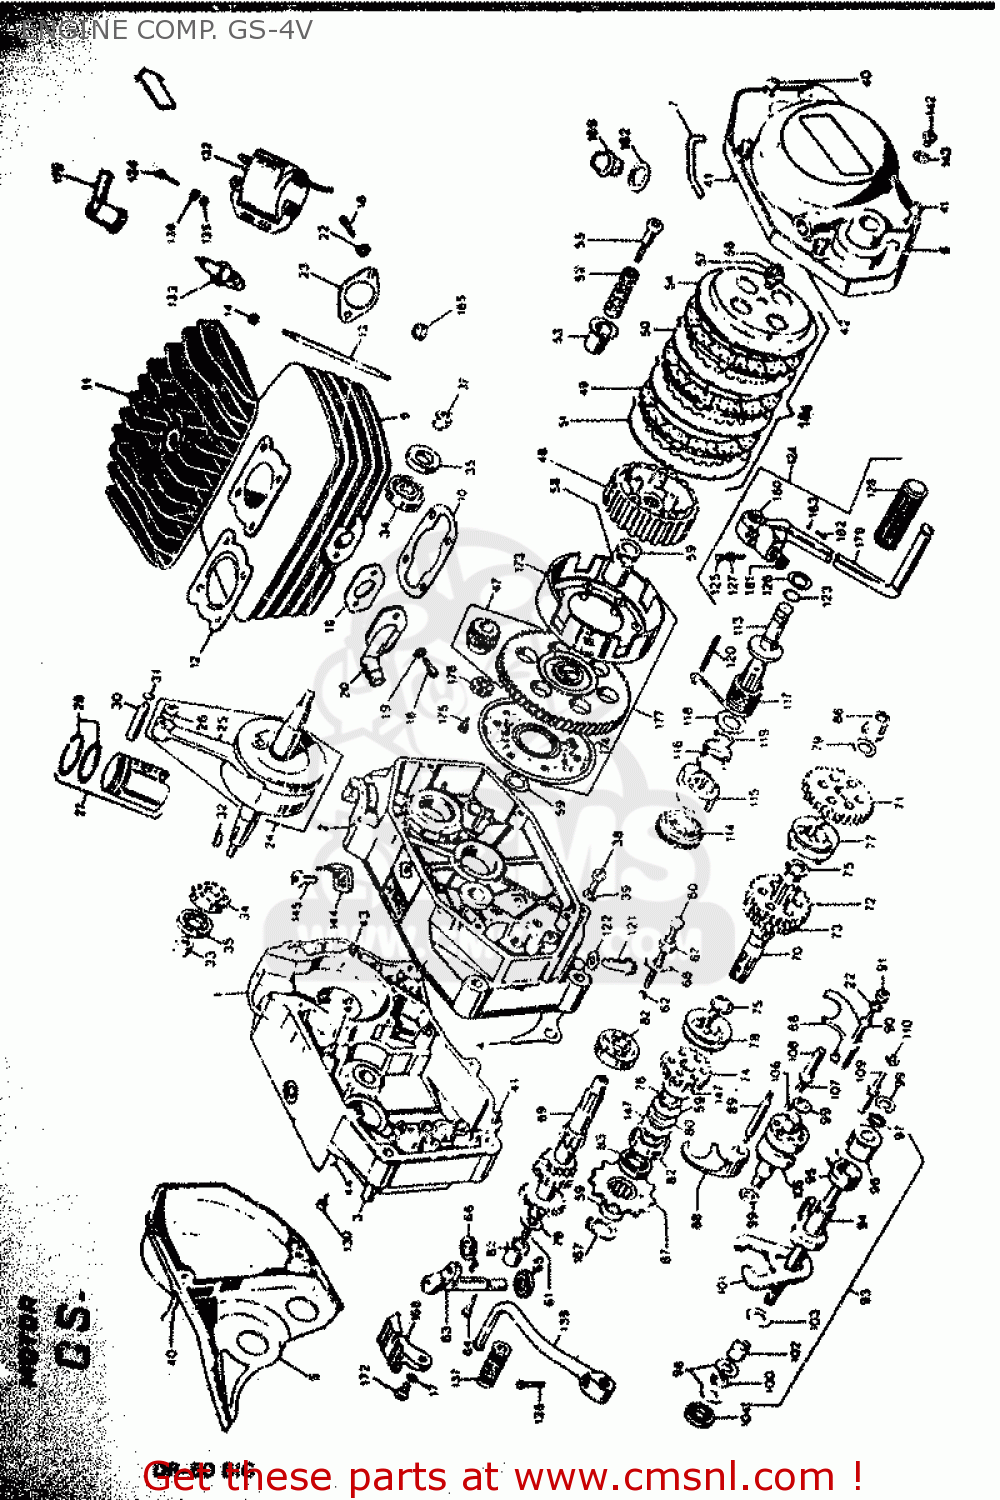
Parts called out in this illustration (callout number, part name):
1	2
2	3
3	PIN
4	GASKET
5	COVER, MAGNETO
6	COVER, CLUTCH
7	GASKET, COVER CLUTCH
9	10
10	11
11	HEAD. CYLINDER1
12	13
13	STUD BOLT
14	NUT M6 DIN 6927
16	GASKET, INTAKE
17	WASHER
18	SCREW
19	WASHER A6 DIN 137
20	PIPE INTAKE
22	WASHER A6 DIN 127
23	GASKET, EXHAUS PIPE
24	CRANKSHAFT ASSY
25	ROD, CONNECTING COMP.
26	27
27	PISTON COMP.
28	RING D=39
30	31
31	CIRCLIP
32	33
33	NUT
34	35
35	AIL SEAL
37	NUT
38	PLUG
39	GASKET
40	41
41	SCREW M6X30
42	43
43	SCREW M6X35
44	45
45	47
47	GEAR, PRIMARY DRIVEN
48	HUB, SLEEVE
49	PLATE, DRIVE
50	PLATE, DRIVEN
51	PLATE, DRIVEN LH
52	53
53	GUIDE CABLE CLUTCH
54	PLATE, PRESSURE
55	56
56	57
57	NUT REGULATION
58	BOSS
59	WASHER
60	61
61	ROD, PUSH
62	63
63	64
64	65
65	OIL SEAL
66	67
67	NUT M12X1,25
68	PLATE NUT
69	COUNTER SHAFT
70	DRIVESHAFT
71	GEAR, 1ST DRIVEN
72	73
73	GEAR, 3RD DRIVEN
74	GEAR, 4TH DRIVEN
75	WASHER SPRING
76	CIRCLIP
77	78
78	79
79	80
80	SPACER
82	83
83	OIL SEAL
85	BUSH
86	BUSH
87	SPROCKET, ENGINE
88	FORK
89	SHAFT, FORK
90	SHAFT, FIXED
91	NUT
93	SELECTOR
94	SHIFTER SHAFT
95	SPRING
96	PROTECTOR SPRING
97	SNAP RING
98	WASHER
99	WASHER
100	CIRCLIP
101	FRONT, CAM
102	103
103	WASHER
104	OIL SEAL
105	CAMSHAFT
106	STEEL BALL
107	SPRING
108	HOUSING STEEL BALL
109	BOLT PAWL SPRING
110	LOCK WASHER
113	114
114	GEAR, KICK STARTER
115	116
116	117
117	SPRING, KICK STARTER
118	TAB WASHER
119	SNAP RING
120	121
121	122
122	GASKET (MCA)
123	O-RING
124	125
125	SCREW M8X30 DIN 933
126	127
127	WASHER 8 DIN 433
128	RUBBER, KICK STARTER
130	132
132	133
133	SPARK PLUG
134	SCREW M6X15 DIN 933
135	WASHER B6 DIN 125
136	TOOTHED LOCK WASHER A6 DIN 6798
137	RUBBER
138	SCREW M7X25 DIN 933
139	142
142	143
143	144
144	GUIDE CABLE CLUTCH
145	147
147	WASHER
162	GASKET, PLUG OIL FILLER
167	SNAP RING
168	GUIDE CHAIN
169	172
172	173
173	174
174	PLATE, STOPPER
175	176
176	RUBBER
177	178
178	CAP ASSY,SPARK
179	180
180	SLEEVE, KICK STARTER
181	SNAP RING
182	183
183	185
185	PAD, RUBBER
